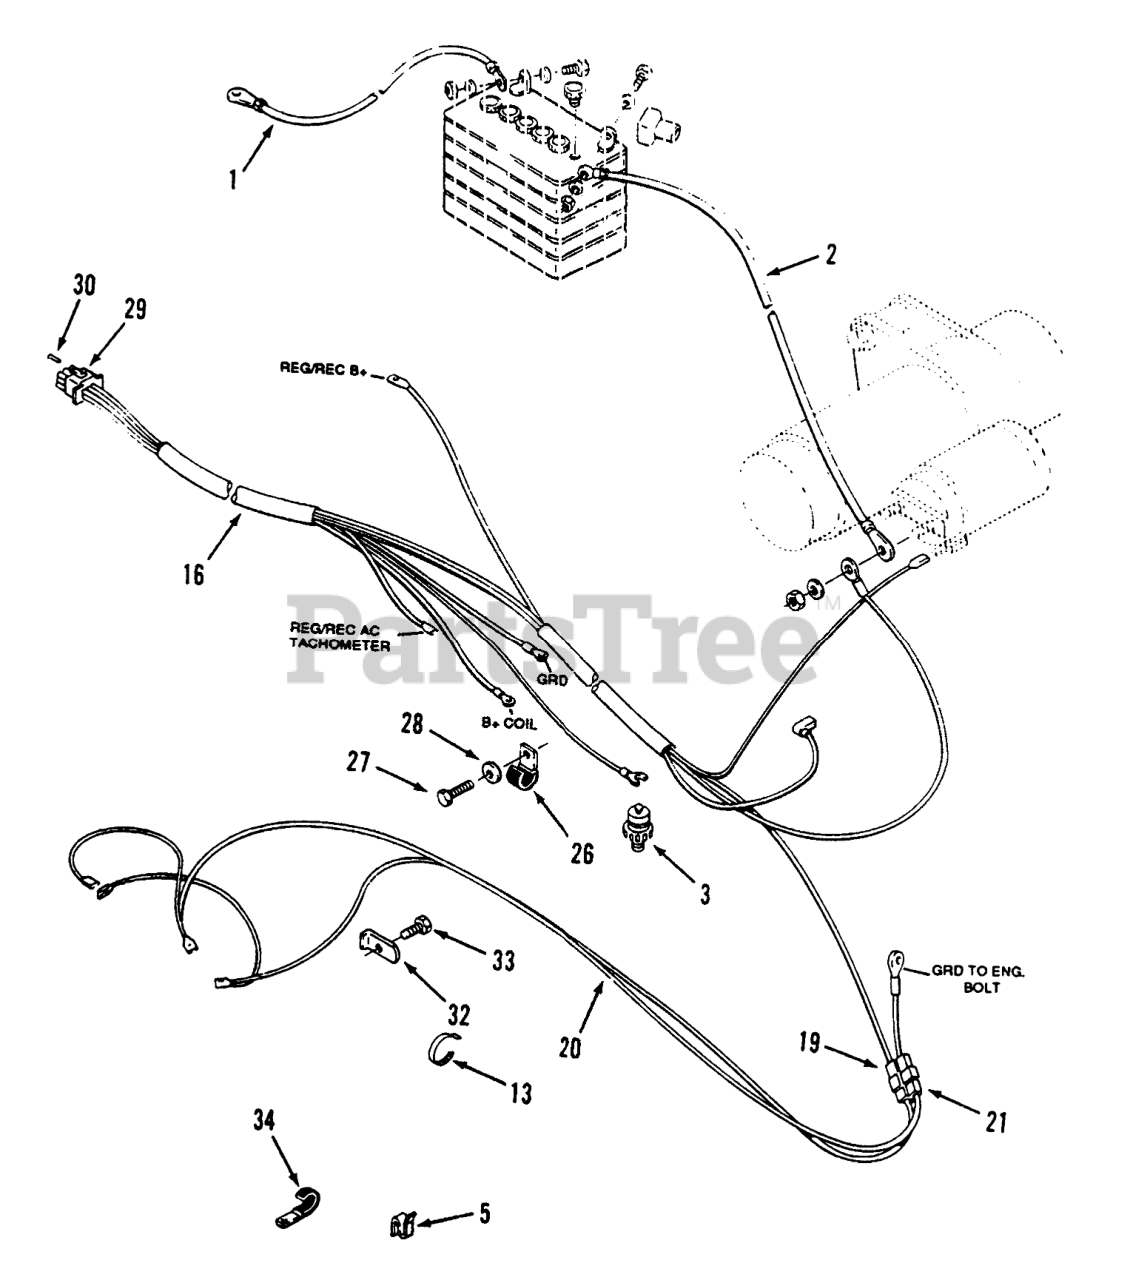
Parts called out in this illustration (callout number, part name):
1	Cable-Battery Ground
2	Cable-Battery (+) to Solenoid
3	SWITCH
4	Boot
5	SPEED CLIP
13	PLASTIC TIE
16	WIRING HARNESS
19	MALE CONNECTOR
20	HARNESS-HEADLIGHT
21	CONNECTOR BODY
26	Clip
27	Bolt
28	LOCKWASHER 1/4 IT
29	CONNECTOR CAP
30	CONTACT SOCKET
32	LOCK-HEADLIGHT
33	Bolt
34	CLIP
